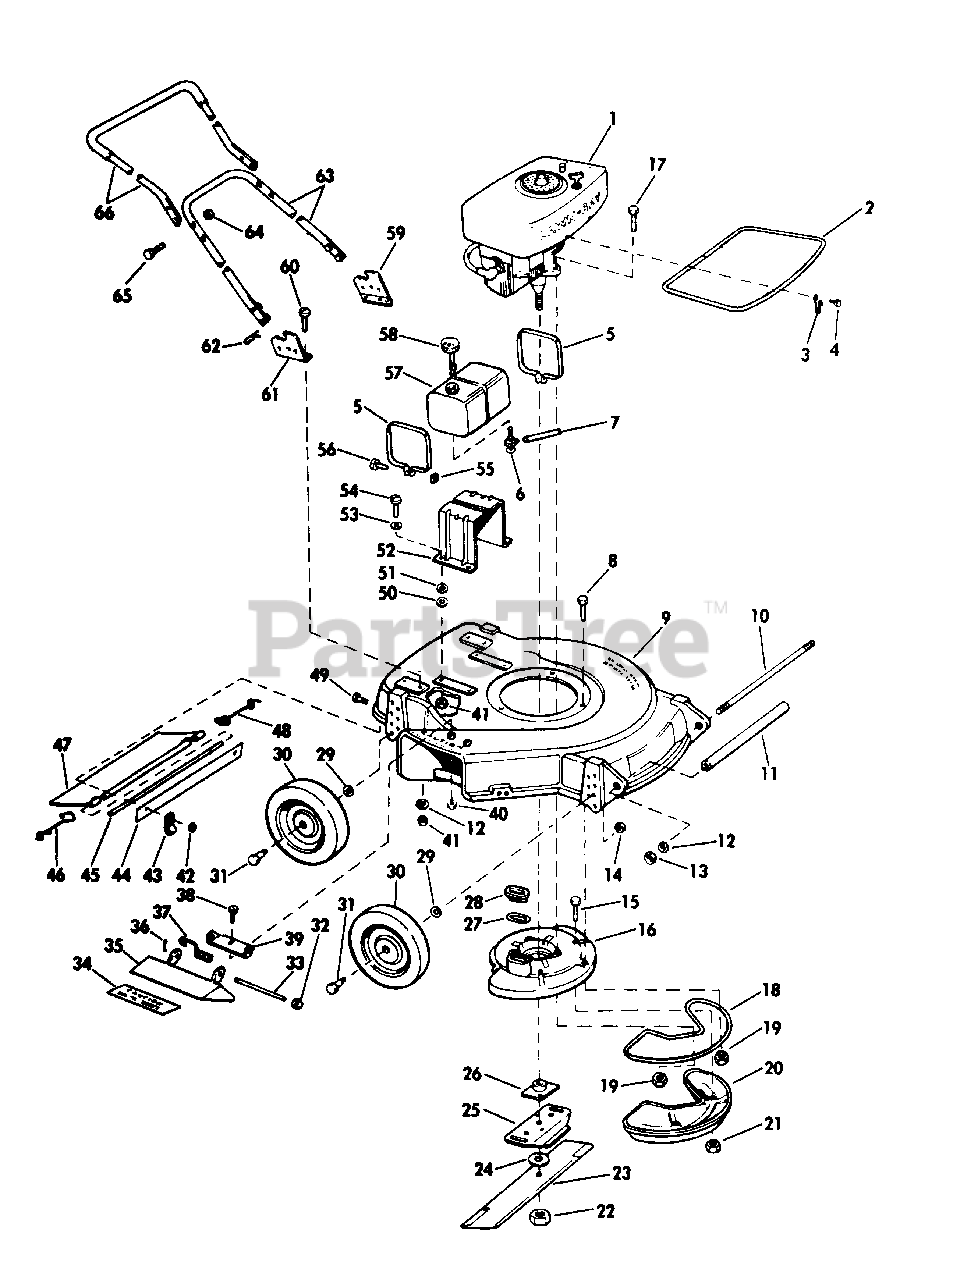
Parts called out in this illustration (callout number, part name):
2	Loop-Arm. Plate Protective Wire
3	Spring-Wire Loop Mounting
4	Screw
5	Strap-Gas Tank
6	Shut-Off Valve & Screen
7	Gas Line
8	Screw-Muffler Plate to Housing
9	Housing & Bar Assembly-21"
10	Rod-Bumper
11	Bumper
12	Washer
13	Nut
14	Nut-Square
15	Screw
16	Muffler Plate Assembly
17	Screw
18	Gasket-Muffler
19	Nut-Nylok
20	Muffler
21	Nut
22	Blade Nut
23	Blade-21"
24	Washer-Blade
25	Stiffener-Blade
26	Collar & Plate
27	Gasket-Exhaust
28	Sleeve-Muffler Gasket
29	Lockwasher
30	Wheel & Tire Assy.-8"
31	Wheel Bolt-Shoulder
32	Push Nut
33	Pin
34	Decal
35	Deflector
36	Cotter Pin
37	Spring
38	Screw
39	Plate
40	Nut
41	Nut
42	Nut
43	Clamp
44	Extension
45	Bar
46	Spring-R.H.
47	Shield
48	Spring-L.H.
49	Screw
50	Washer
51	Grommet
52	Bracket-Gas Tank
53	Washer
54	Screw
55	Nut-Plain Square
56	Screw-Strap to Bracket
57	Gas Tank Assy.
58	Fuel Gauge Assy.
59	Handle Bracket, Left
60	Screw-Slotted
61	Handle Bracket, Right
62	Hair Pin
63	Handle Bottom & Pin Assy.
64	Nut Stop-Handle
65	Screw-Handle
66	Top Handle Section & Grip Assy.
